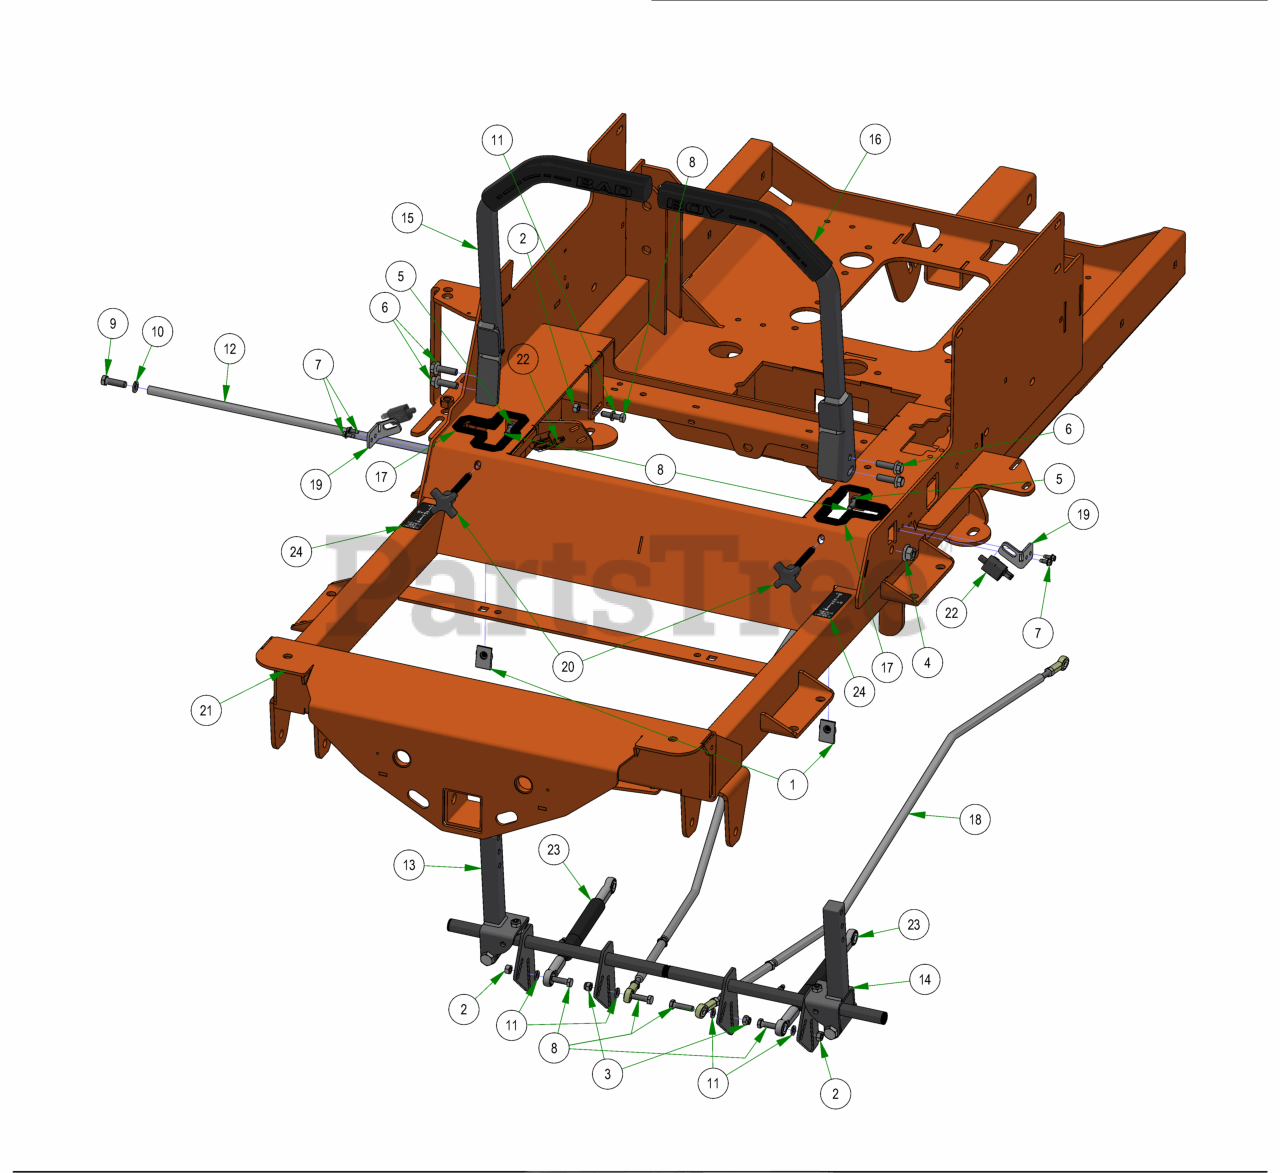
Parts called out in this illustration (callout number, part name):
1	Extruded Nut 3/8"-16 3/4" Hole Center With Patch
2	5/16-18 HEX NUT ZINC
3	5/16-18 NYL INS L/N ZC
4	1/2-13 NYLON INSERT FLANGE LOCKNUT ZINC
5	5/16-18 HEX SERRATED FLANGE NUT HARD/ZINC
6	3/8-16 X 1 1/4 HEX WASHER UNSLOT MACHINE SCREW ZINC GR5
7	12-24 X 1/2 HEX WASHER UNLSOT F TCS ZINC
8	5/16-18 X 1-1/4 HEX C/S (GR.5) ZC
9	3/8-16 X 1-1/4 HEX CAP SCREW (GR.5) ZINC
10	3/8 SPLIT LOCKWASHER ZINC
11	5/16 SPLIT LOCKWASHER ZINC
12	2019 Steering Actuator Rod
13	R Series Square Drive Arm Actuator RH Assembly
14	R Series Square Drive Arm Actuator LH Assembly
15	R Series Square Drive Arm RH Assembly
16	R Series Square Drive Arm LH Assembly
17	Snap-in Drive Arm Bushing
18	2019 Renegade Push Rod Assembly
19	Push In Arm Safety Switch R Series Bracket
20	Speed Limiting Knob 3/8-16X 3"
21	2022 Horizontal Diesel Frame
22	Rail Mount Safety Switch
23	2019 SROID Damper With Spherical Rod Ends
24	2018 LH/RH Steering Control Decal Roll
